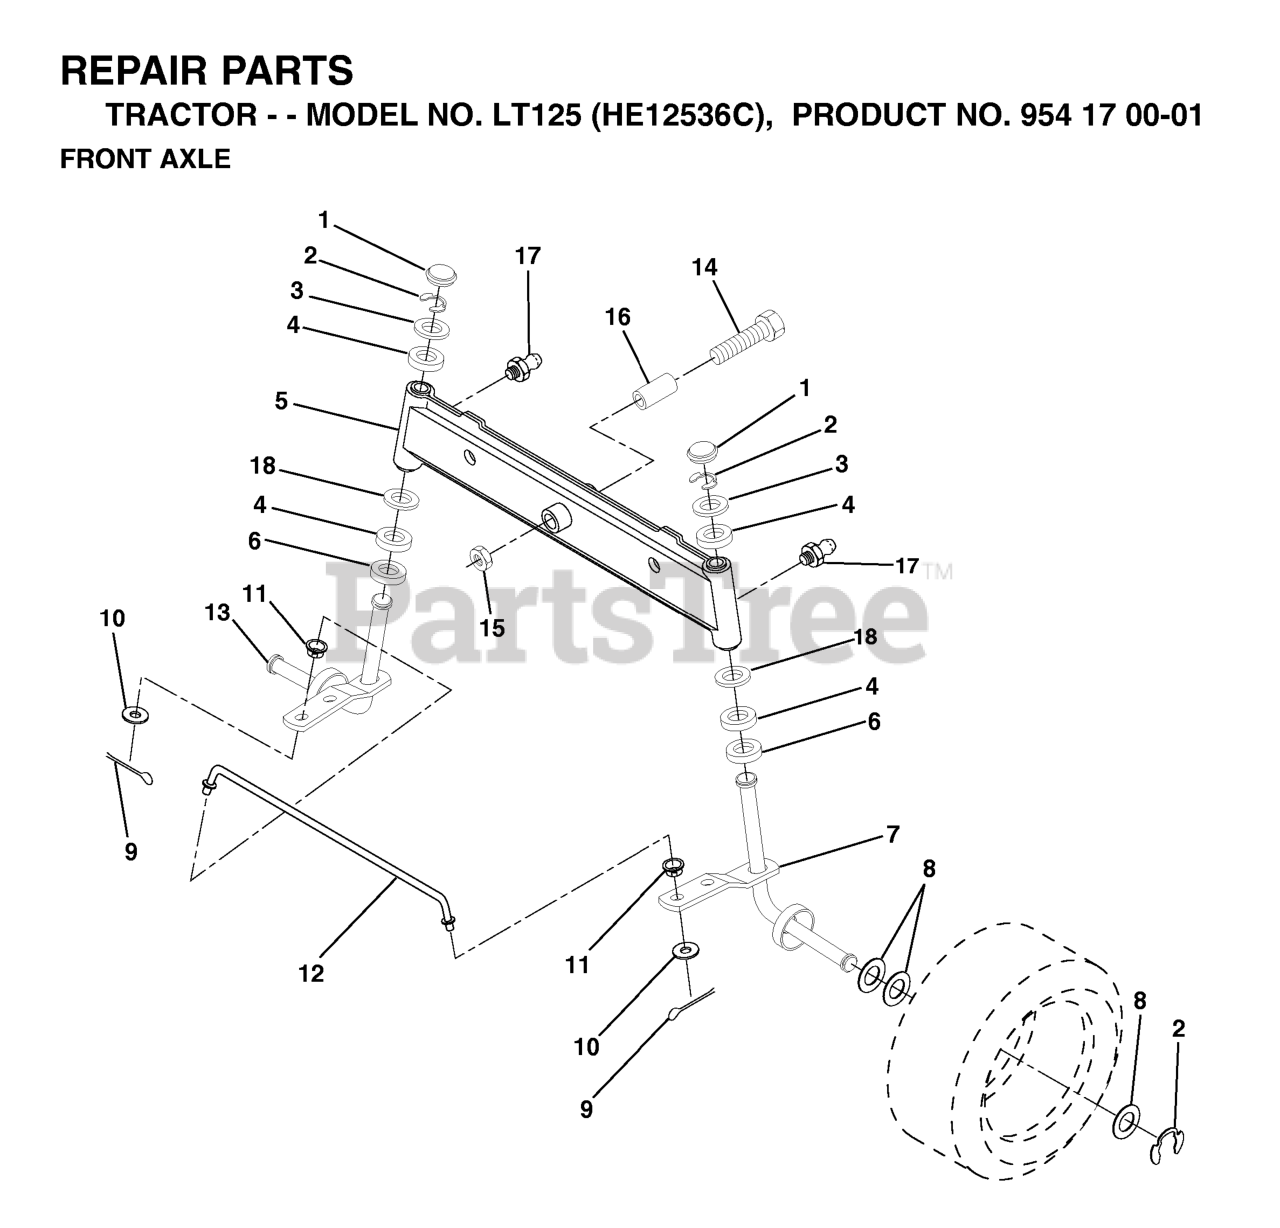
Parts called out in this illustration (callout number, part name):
1	CAP.SPINDLE.BLACK
4	BRNG T
6	THRUST WASHER
9	COTTER PIN
10	WASHER
11	BUSHING.DRAGLINK (2 2)
12	TIE ROD
13	SPINDLE.ASSEM.LH
14	Bolt, Hex Head 5/8-11 x 3-1/2
15	NUT-LOC,FLANGE LT
16	BEARING
17	ZERK M
